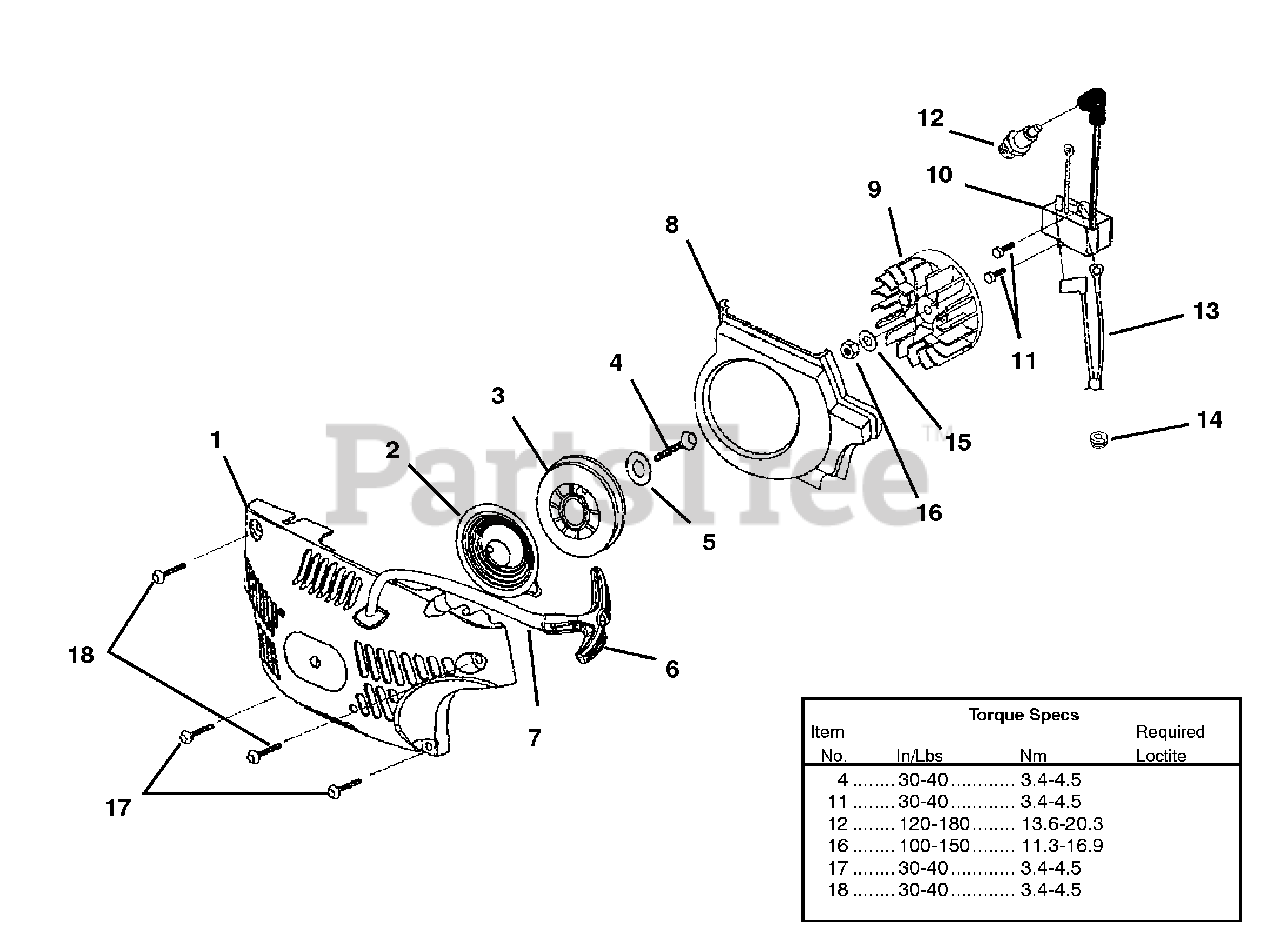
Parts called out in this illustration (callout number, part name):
1	Starter Kit
2	Spring & Container
3	Pulley, Starter
4	Screw, Thread Form (10-14 x 5/8")
5	Washer, Retaining
6	Grip, Starter
7	Rope, Starter 46"
8	Baffle, Fan Housing
9	Rotor & Starter Pawl
10	Ignition Kit
11	Screw, Thread Form (8-32 x 5/8")
12	Spark Plug
13	Ignition Switch Harness
14	Grommet, Wire Harness (Split)
15	Washer, Flat
16	Nut, Jam
17	Screw, Truss Hd. (10-14 x 7/8")
18	Screw, Truss Hd. (10-14 x 5/8")
